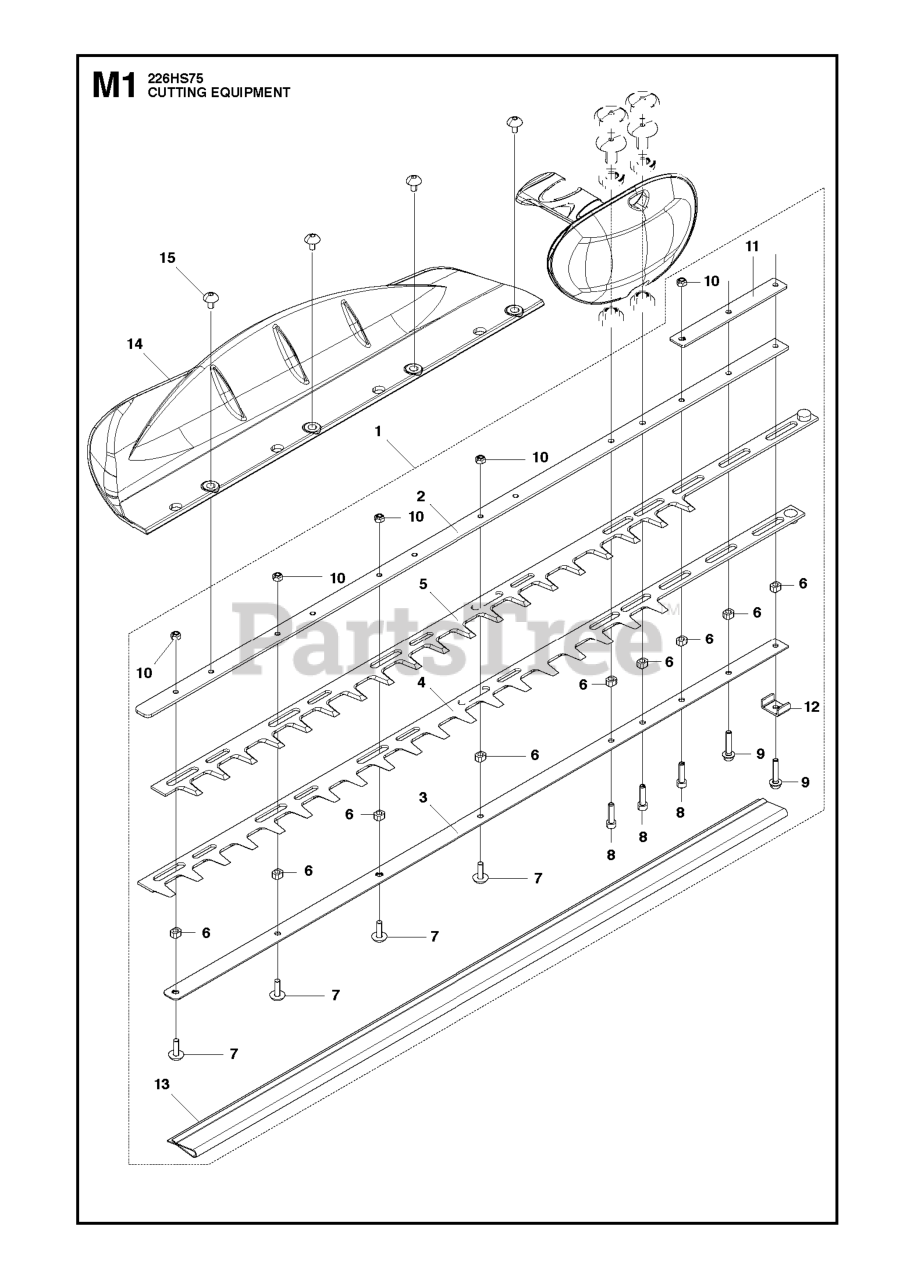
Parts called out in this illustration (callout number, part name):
2	PLATE UPPER
3	PLATE LOWER
8	BOLT
